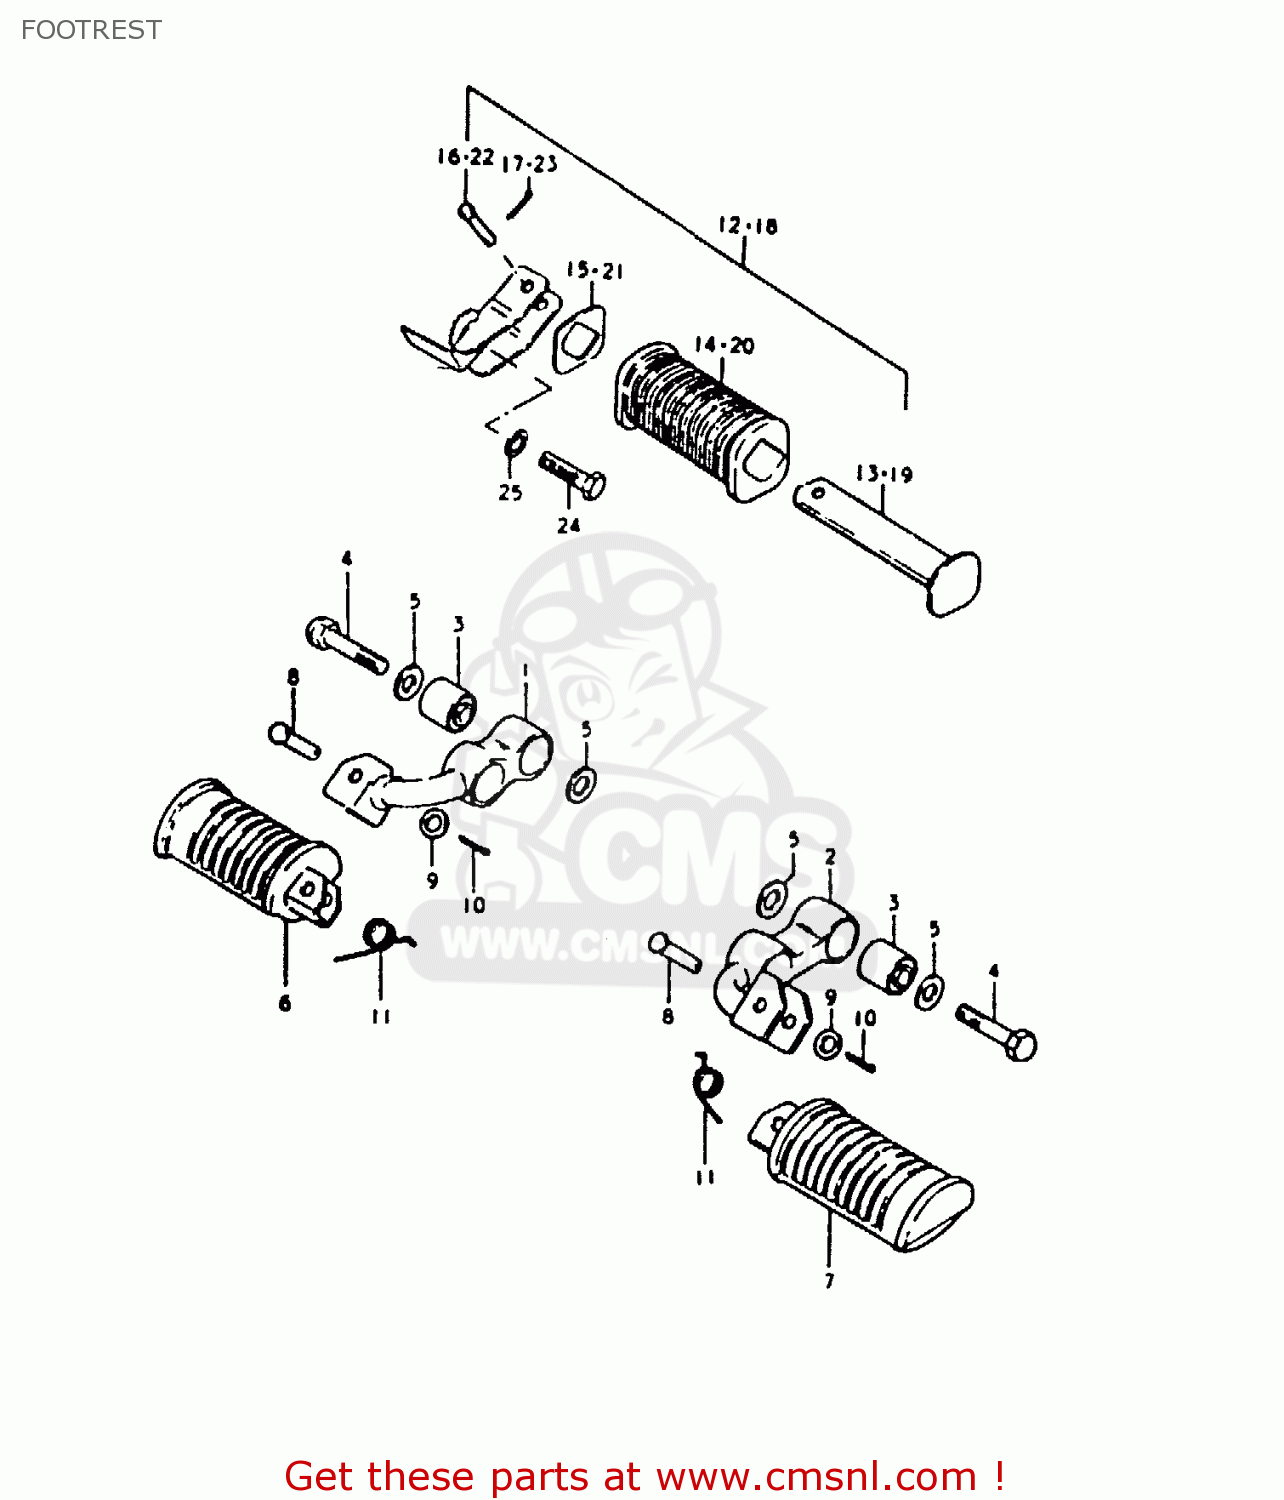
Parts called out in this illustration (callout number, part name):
1	BAR,FRONT FOOTREST
2	BAR,FRONT FOOTREST,LEFT
3	BUSH
4	BOLT
5	WASHER (10.1X21X2.3)
6	RUBBER,FRONT FOOTREST
7	FOOTREST
8	PIN
9	WASHER
10	PIN 20X20
11	SPRING
12	FOOTREST ASSEMBLY,REAR
13	BAR,REAR FOOTREST
14	RUBBER, LH
15	WASHER,REAR FOOTREST RUBBER
16	PIN
17	PIN
18	FOOTREST ASSEMBLY,REAR
19	BAR,REAR FOOTREST,LEFT
20	RUBBER,PILLION FOOTREST
21	WASHER,PILLION FOOTREST RUBBER
22	PIN
23	PIN
24	BOLT 10X30
25	LOCK WASHER
